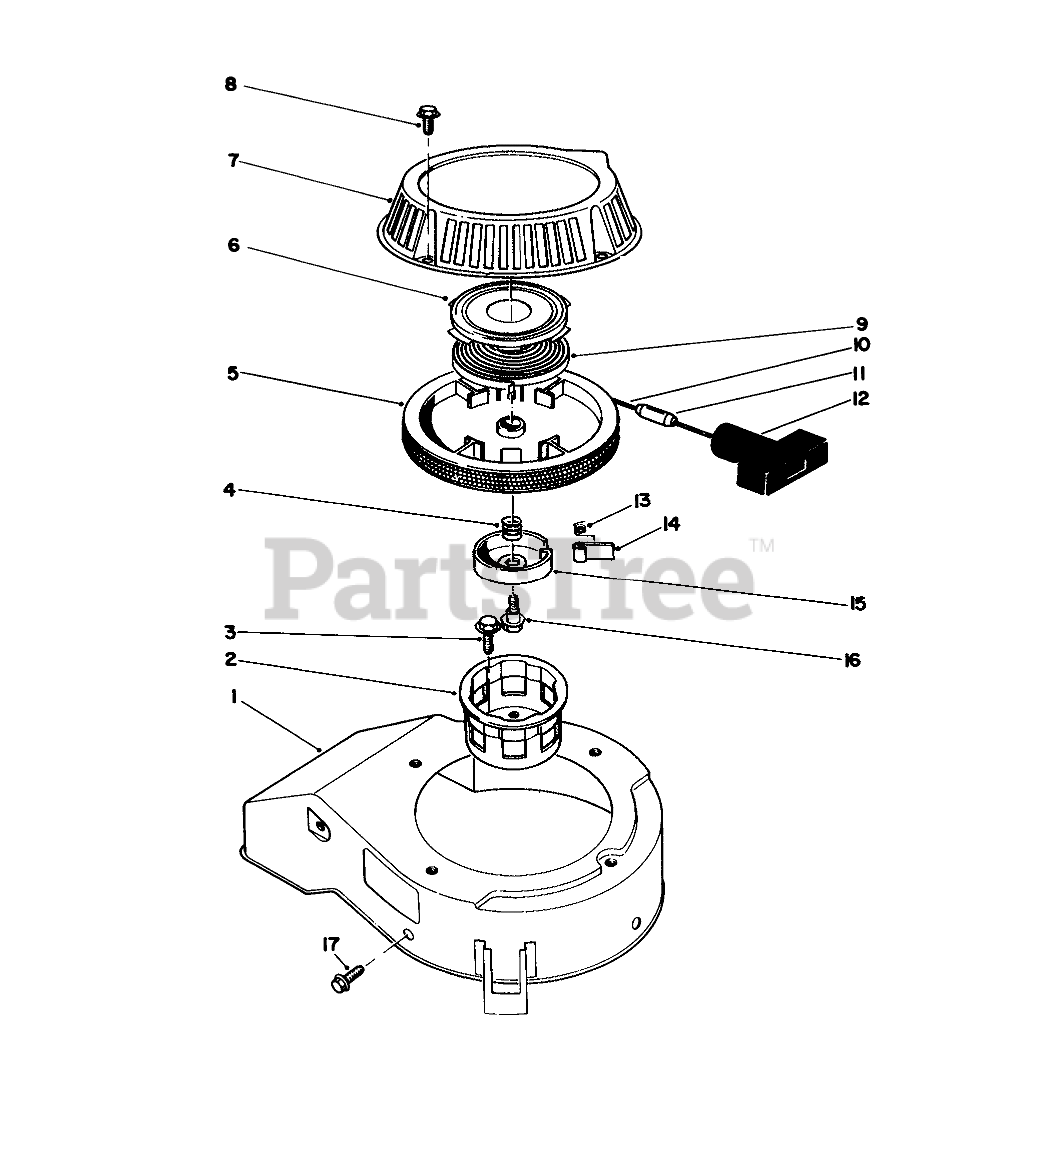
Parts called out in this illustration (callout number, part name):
1	COVER
2	CUP - STARTER
4	SPRING
6	Retainer-Recoil Spring
8	SCREW-HHF
9	Spring-Recoil
10	ROPE-STARTER
12	HANDLE-RECOIL
13	SPRING
15	RETAINER
